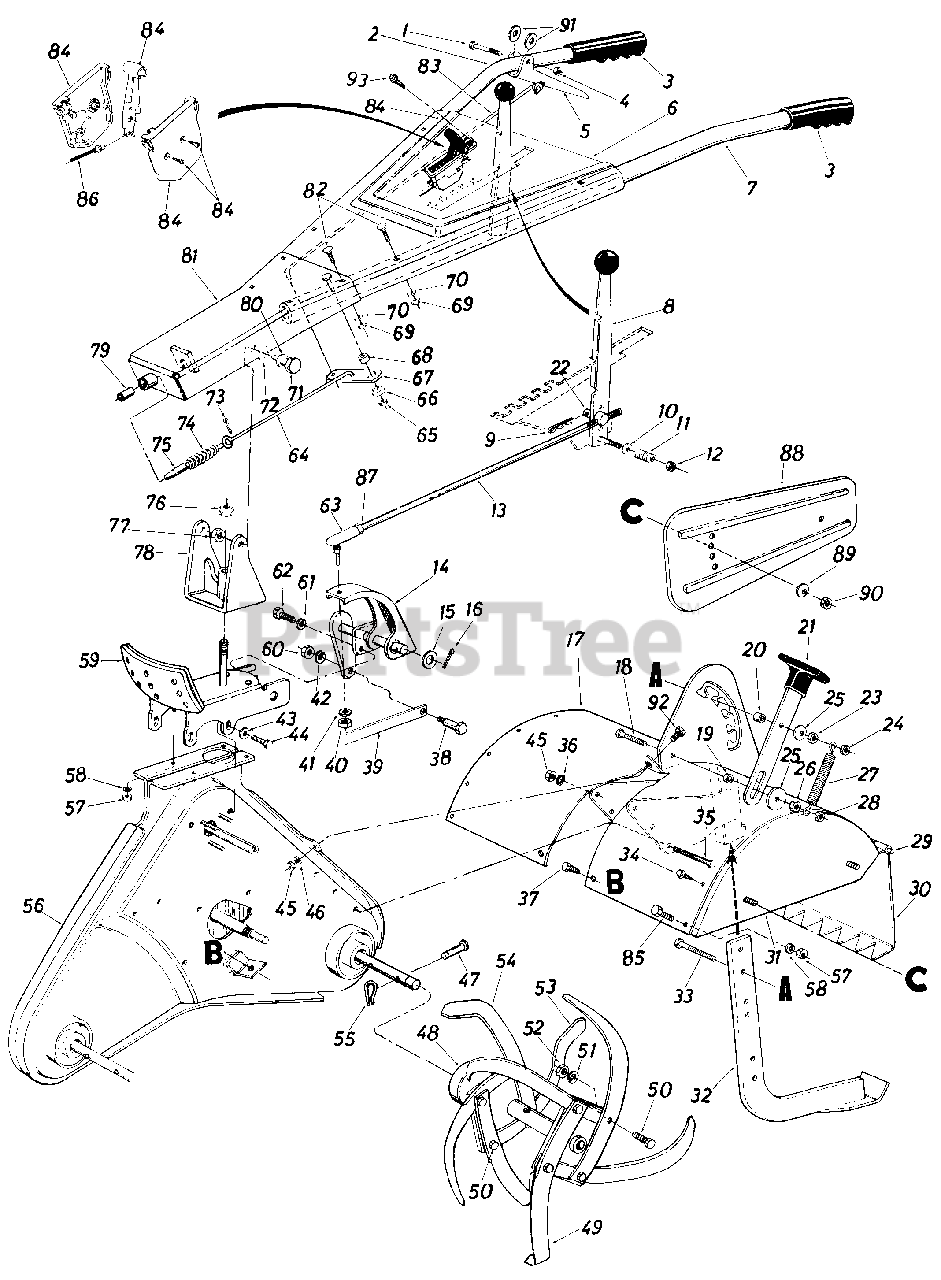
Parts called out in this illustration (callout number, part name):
1	Hex Bolt 1/4-20 x 1.75" Lg.
2	Handle-R . H .
3	Grip
4	Hex Cent. L-Nut 1/4-20 Thd.
5	Clutch Grip
6	Handle Panel Ass'y.
7	Handle-L.H.
8	Clutch Handle Ass'y.
9	Hairpin Cotter
10	Belleville Wash. .38" I.D.
11	Compression Spring .88" O.D. x .81" Lg.
12	Hex Cent. L-Nut 3/8-24 Thd.
13	Gear Shift Rod
14	Pivot Horn Ass'y.
15	Fl-Wash. .630 I.D. x 1.0" O.D. x .063
16	Cotter Pin 118" Dia. x .75"
17	Tine Shield Ass'y.
18	Hex Bolt 3/8-16 x 1.5" Lg.
19	Spacer .38 I.D. x .50 O.D. x .18 Lg.
20	Spacer .38 I.D. x .50 O.D. x .38 Lg.
21	Depth Bar Handle Ass'y. w/ Knob
22	Ferrule
23	Hex Nut 3/8-16 Thd.
24	Hex Ins. L-Nut 3/8-16 Thd.
25	Fl-Wash. .38 I.D. x 1.50 O.D. x .13
26	Hex Nut 3/8-16 Thd.
27	Spring-Depth Bar
28	Hex Ins. L-Nut 3/8-16 Thd.
29	Hinge Rod
30	Tine Shield Hinge Flap Ass'y.
31	Side Cover Tine Shield-L.H.
32	Depth/Drag Bar Ass'y.
33	Hex Bolt 3/8-16 x 1.75" Lg.
34	Hex Wash. Hd. Self-Tap Scr. 5/16-18 x .62" Lg.
35	Hex Bolt 3/8-24 x 3.0" Lg.
36	L-Wash. 3/8" I.D.
37	Hex Wash. Hd. Self-Tap Scr.
38	Shoulder Bolt .50" Dia. x .25"
39	Control Bracket
40	Hex Ins. L-Nut 3/8-24 Thd.
41	L-Wash. 3/8" I.D.
42	L-Wash. 3/8" I.D.
43	Belleville Wash.
44	Hex Wash. Hd. Self-Tap Scr.
45	Hex Nut 3/8-24 Thd.
46	L-Wash. 3/8" I.D.
47	Clevis Pin
48	Tine Adapter Ass'y.
49	L.H. Tine Ass'y. Comp.
50	Hex Bolt 3/8-24 x 1.25" Lg.
51	L-Wash. 3/8" I.D.
52	Hex Nut 3/8-24 Thd.
56	Chain Case Ass'y. Comp.
57	Hex Nut 5/16-18 Thd.*
58	L-Wash. 5/16" I.D.
59	Handle Positioner Ass'y.
60	Hex Ins. L-Nut 3/8-16 Thd.
61	L-Wash. 5/16" I.D.
62	Hex Wash. Hd. Self-Tap Scr.
63	Rod End 3/8-24 Thd.
64	Lower Handle Control Rod
65	Hex Nut 5/16-18 Thd.
66	Pivot Handle Brg.
67	Pivot Handle Link
68	Bushing Wash.
69	Hex Nut 5/16-18 Thd.
70	L-Wash. 5/16" I.D.
71	Shld. Bolt .500" Dia. x .660
72	Belleville Wash. .505" I.D. x 1.00" O.D.
73	Cotter Pin 118" Dia. x .75"
74	Compression Spring
75	Locking Pin
76	Hex Ins. L-Nut 5/8-16 Thd.
77	Hex Top L-Nut 3/8-16 Thd.
78	Pivot Brkt. Ass'y.
79	Sleeve Brg. .50" I.D. x .62" O.D. x 1.12" Lg.
80	Fl-Wash. .50" I.D. x 1.00" O.D. x .090
81	Handle Mtg. Brkt. Ass'y.
82	Carriage Bolt 5/16-18 x 1.75"
83	Handle Lock Rod
84	Throttle Control Box Ass'y.
85	Hex Bolt 5/16-18 x .75" Lg.
86	Throttle Control Wire
87	Hex Jam Nut 3/8-24 Thd.
90	Hex Nut 5/16-18 Thd.
91	Fl-Wash. 1/4" I.D.
92	Hex Bolt 3/8-24 x .75" Lg.
93	Self-Tap Scr. #10 x 1/2" Lg.
